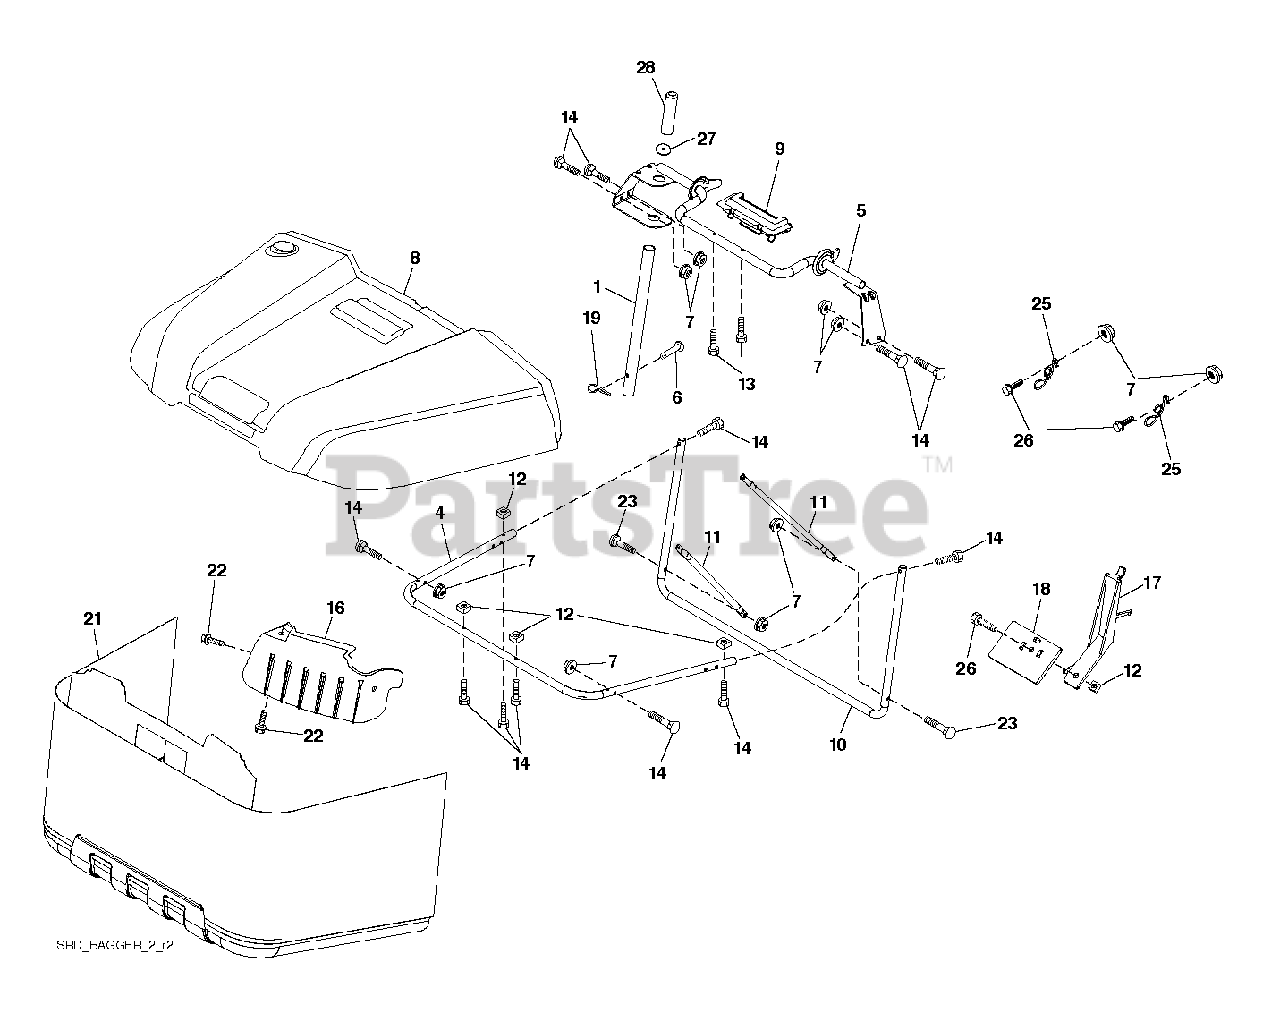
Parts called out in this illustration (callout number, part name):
1	TUBE.PNT.HDL.BAGGER.
6	RIVET,DRILLED
7	NUT T
19	PIN.COTTER.5/16.BOW TI
22	SCREW.HI-LO.CONSOLE
26	SCREW HEX CRT
28	GRIP.HANDLE.BLACK
